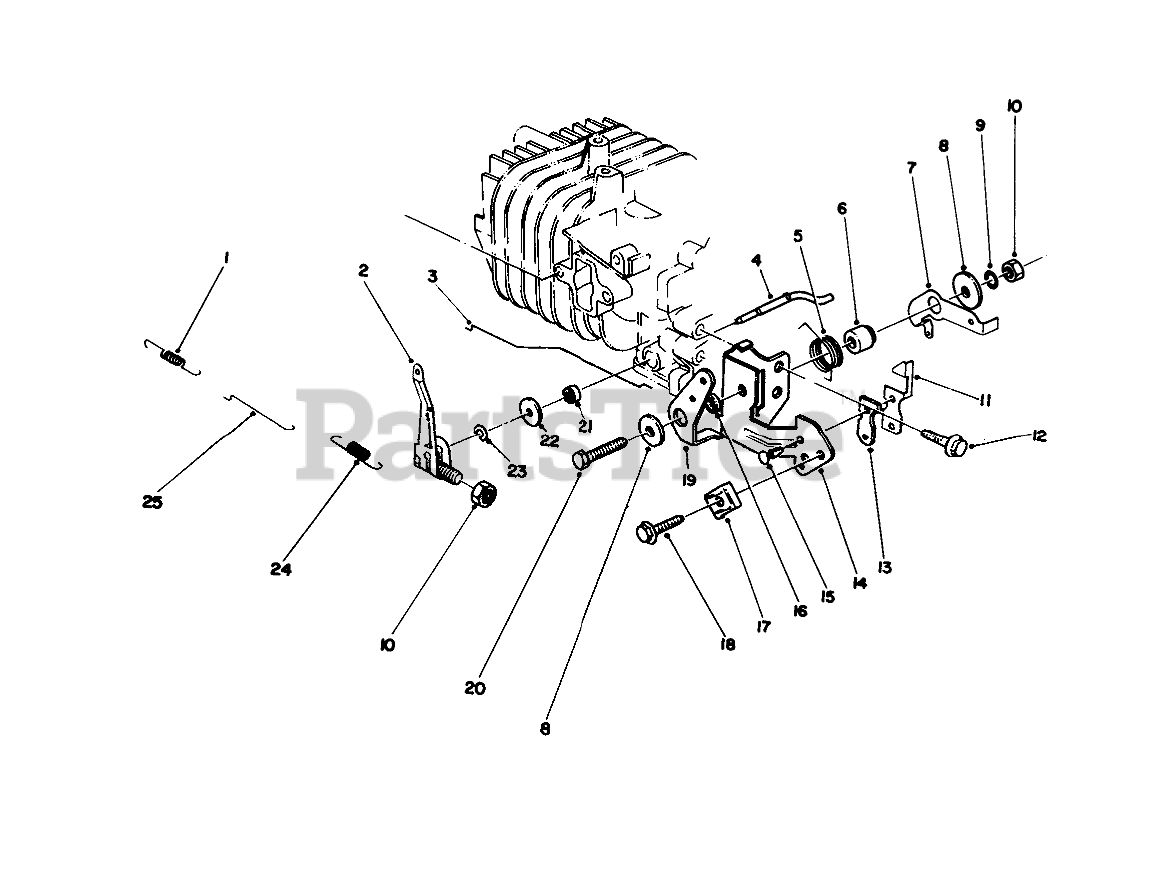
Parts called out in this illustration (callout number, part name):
1	SPRING
2	ARM-GOVERNOR
3	ROD-CHOKE
4	SHAFT
5	SPRING-CHOKE LEVER
6	Gov Lever Spacer
7	LEVER-SPRING, GOVERNOR
8	WASHER
9	LOCKWASHER
11	TERMINAL-KILL SWITCH
13	INSULATOR-KILL SWITCH
14	BRACKET-THROTTLE, CONTROL
15	RIVET
16	SPACER-CHOKE LEVER
17	CLAMP
19	LEVER-CONTROL, CHOKE
21	SEAL-OIL
22	WASHER
23	E-RING
24	SPRING-GOVERNOR
25	ROD-CARBURETOR
